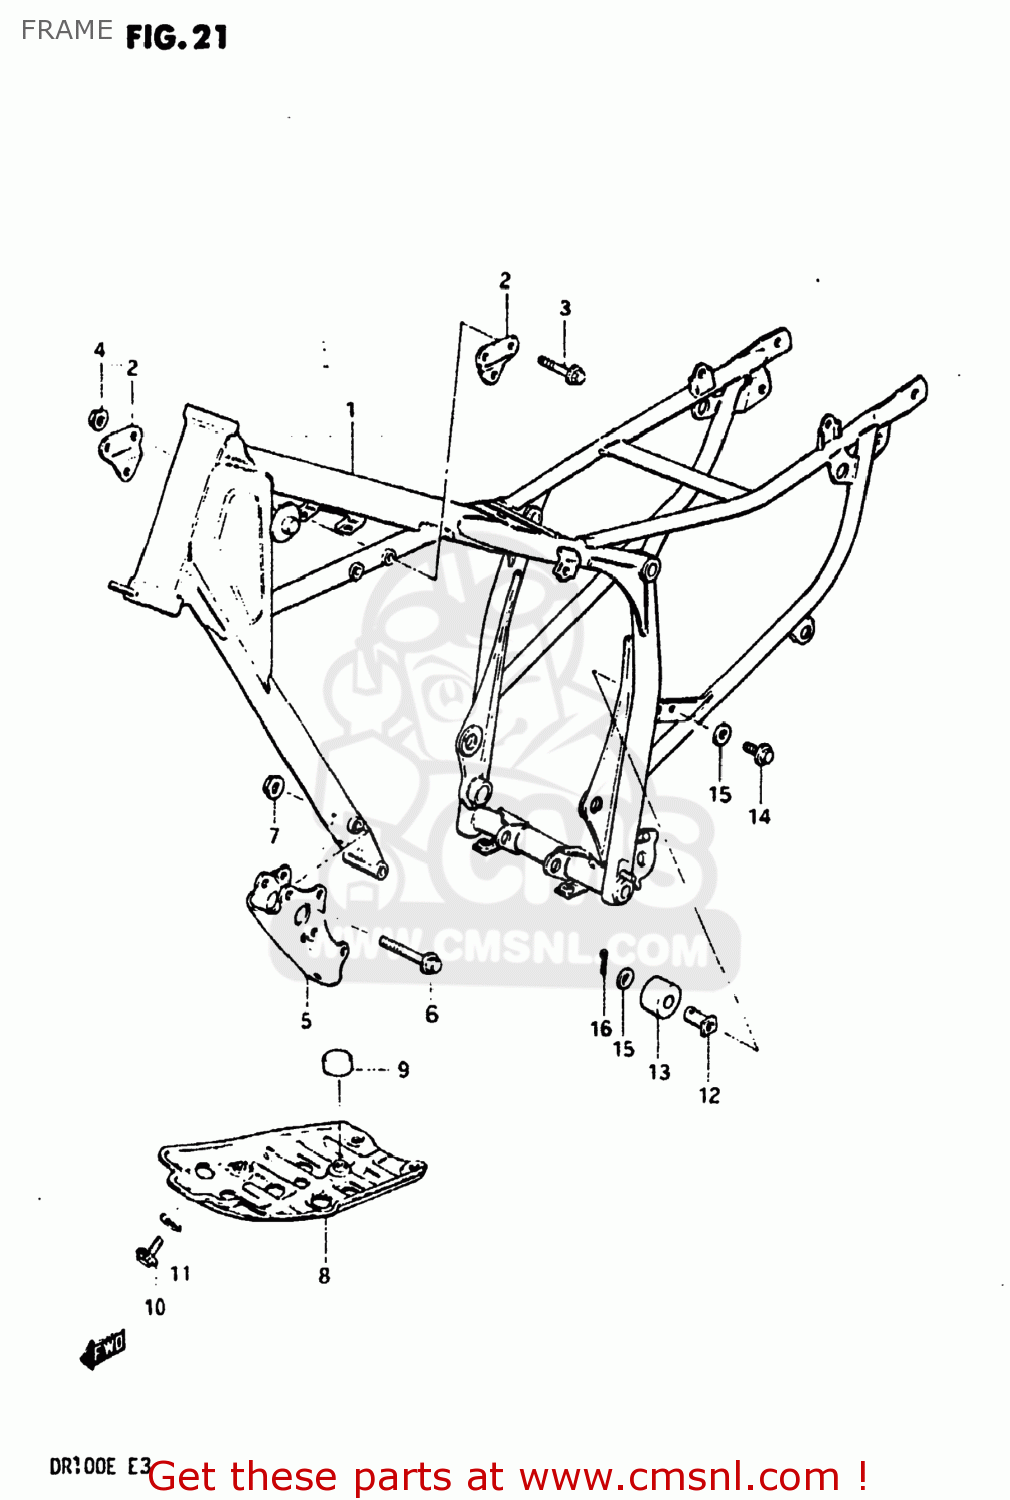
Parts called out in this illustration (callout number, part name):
1	FRAME
2	PLATE,ENGINE MOUNTING
3	BOLT(8X50)
4	NUT
5	PLATE,ENGINE MOUNTING
6	BOLT 8X67
7	NUT
8	PROTECTOR,ENGINE
9	CUSHION
10	BOLT
11	WASHER
12	BOSS,CHAIN CONTROL
13	ROLLER,CHAIN LENGTH CONTROLLER
14	BOLT
15	WASHER
16	PIN 25X20
